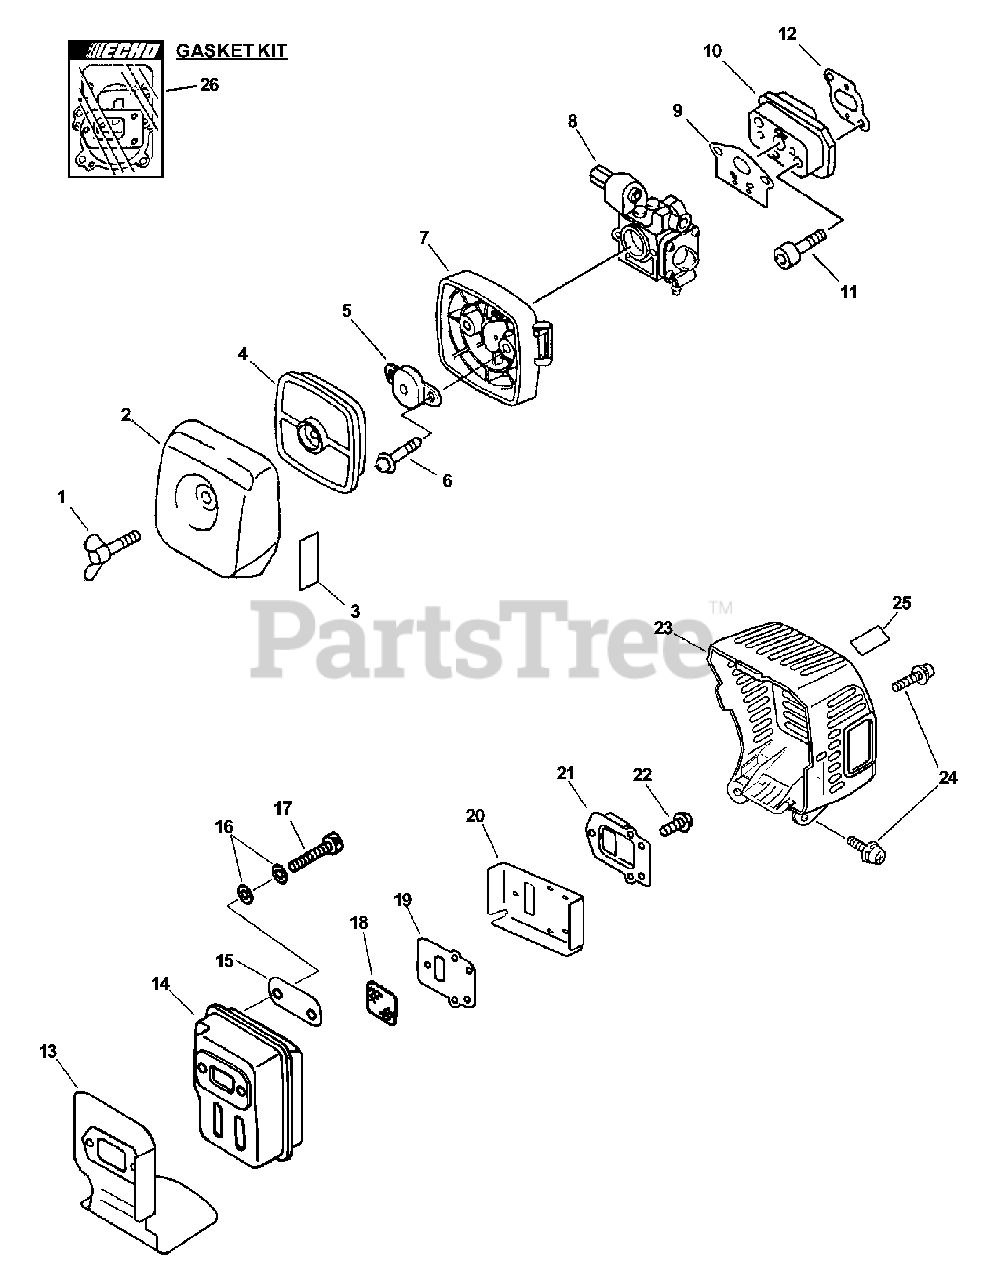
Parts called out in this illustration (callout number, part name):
1	THUMBSCREW
2	COVER, AIR FILTER - GRAY
3	LABEL - CHOKE
4	FILTER, AIR - SINGLE LAYER
5	PLATE, PREVENT
6	SCREW - 5X60
7	CASE, AIR FILTER - GRAY
8	CARBURETOR RB-K57A
9	GASKET, INTAKE
10	INSULATOR, INTAKE
11	SCREW - 5X25
12	GASKET, INTAKE
13	SHIELD, EXHAUST
14	MUFFLER
16	WASHER - CONICAL
17	SCREW - 5X55
18	SCREEN, SPARK ARRESTOR
19	GASKET, EXHAUST
20	GASKET, EXHAUST
21	GUIDE, EXHAUST
22	SCREW - 4X10
23	COVER, EXHAUST
24	SCREW - 5X12
25	LABEL - HOT SURFACE
26	GASKET KIT
